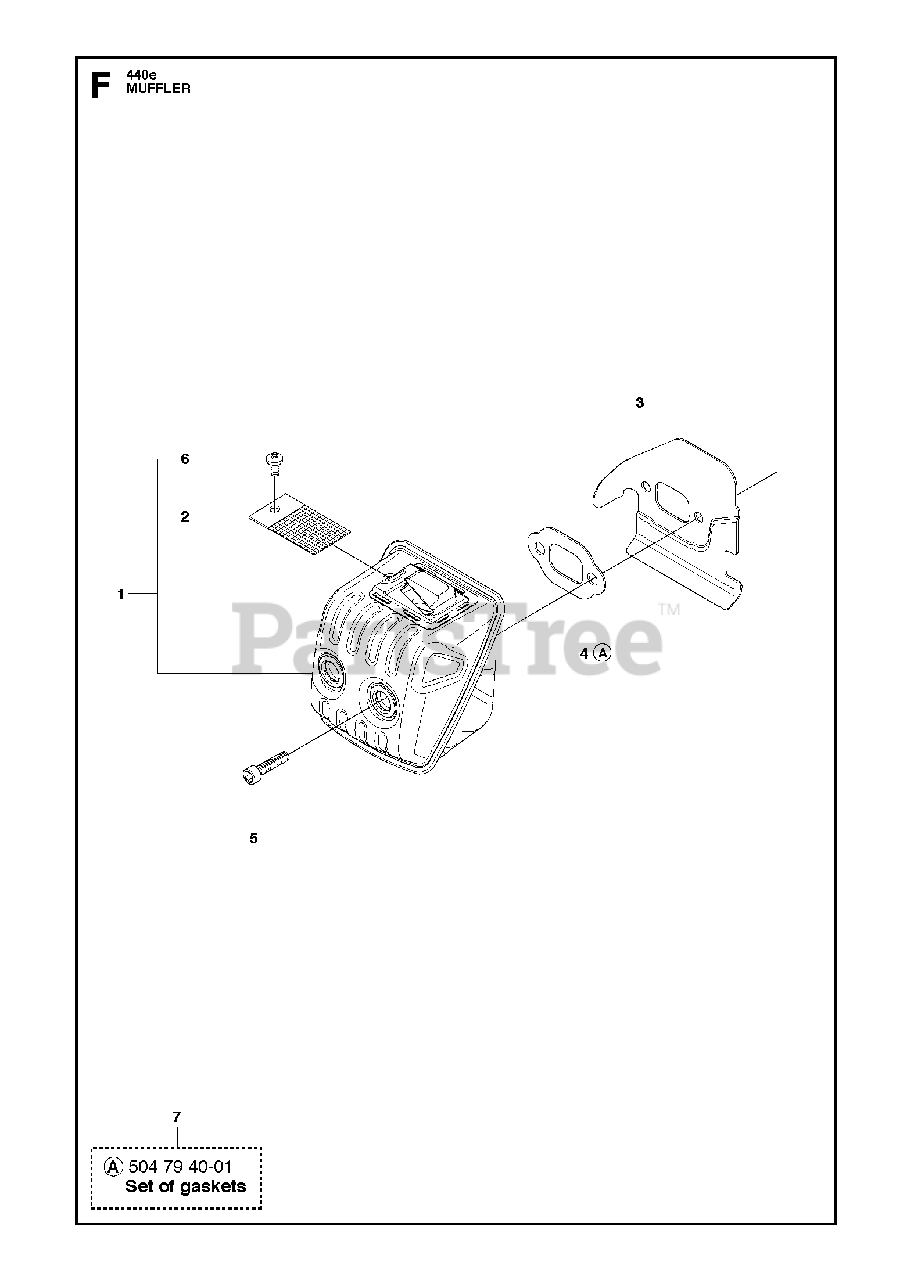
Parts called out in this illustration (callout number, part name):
1	MUFFLER ASSY
2	RP SCREEN
3	HEAT DEFLECTOR
4	RP GASKET
5	SCREW MC6S 6X16
6	SCREW
7	GASKET SET
